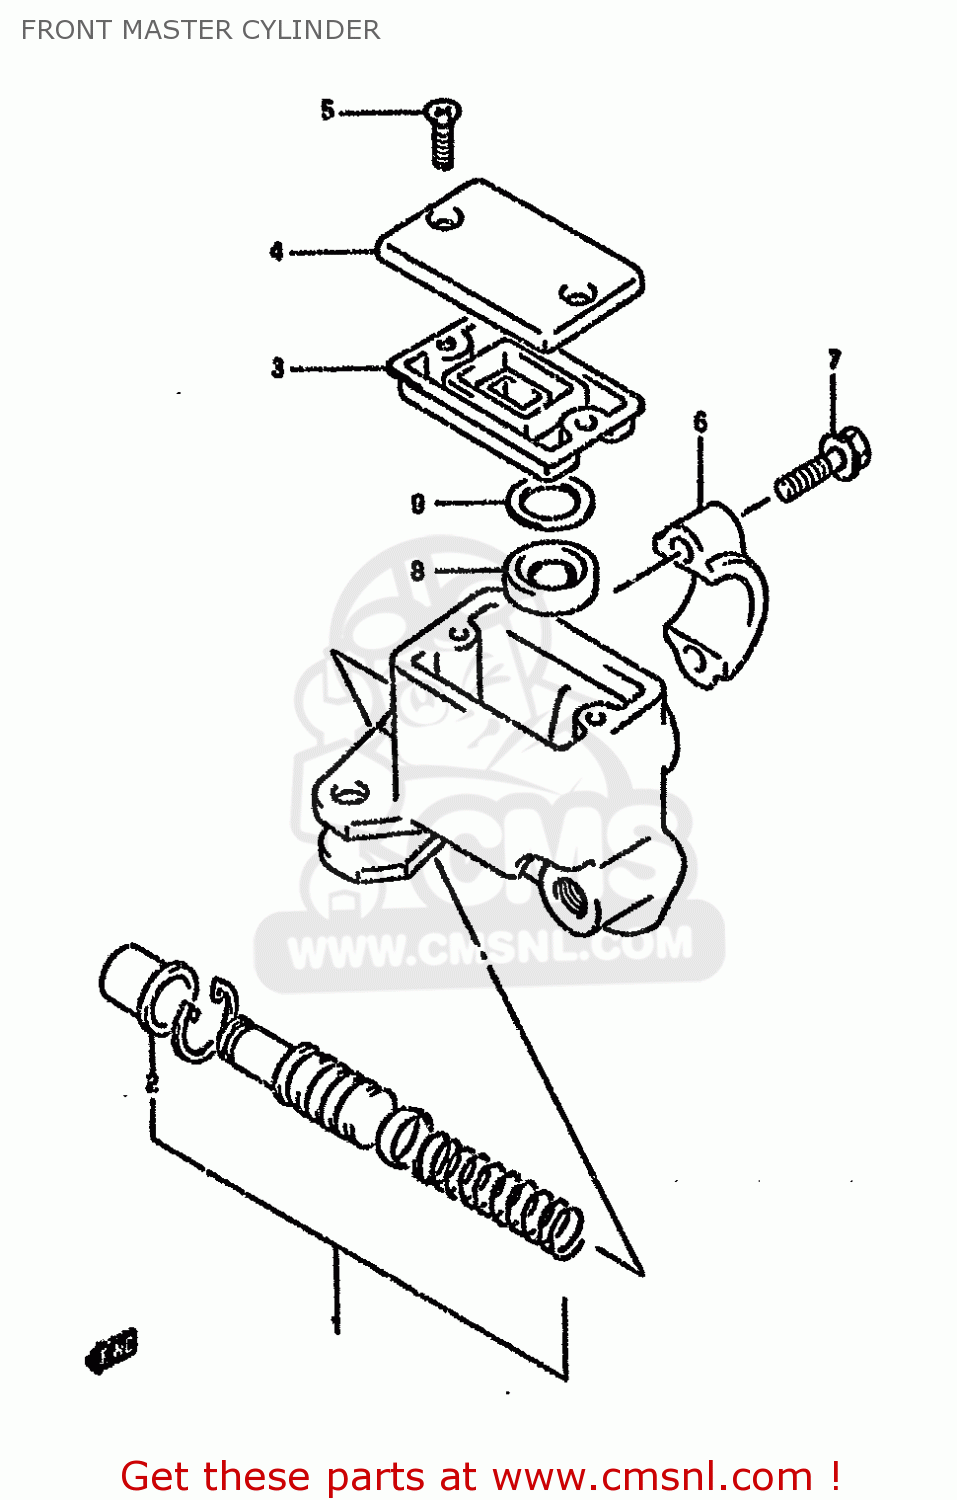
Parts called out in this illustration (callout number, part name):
1	PISTON & CUP SET
2	BOOT
3	DIAPHRAGM
4	CAP
5	SCREW
6	HOLDER
7	BOLT(6X25)
8	SEPERATOR
9	PLATE
